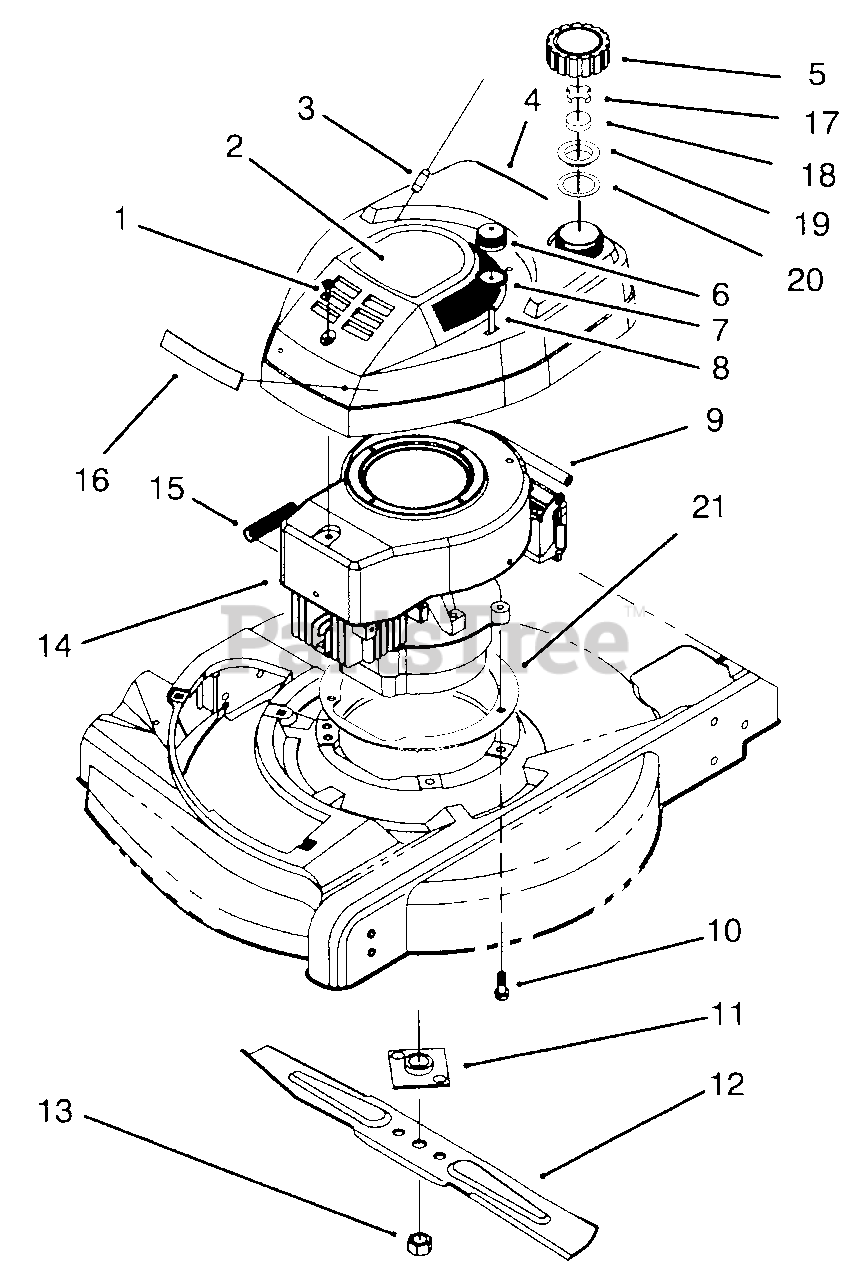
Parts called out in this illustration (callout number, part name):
1	Screw-Sems
2	Decal-Shroud
3	Rope-Stop
4	Tank & Shroud Assembly
5	Gas Cap Assembly (Incl. Ref. #17-20)
6	Bulb-Primer
7	Body-Primer
8	Hose-Primer
9	Line-Gas
10	Screw-Engine
11	Plate & Collar Assembly
12	Blade-21"
13	Nut-Blade
14	Engine
15	Spring-Compression
16	Applique-Shroud
18	Baffle-Foam
21	Plate-Engine
